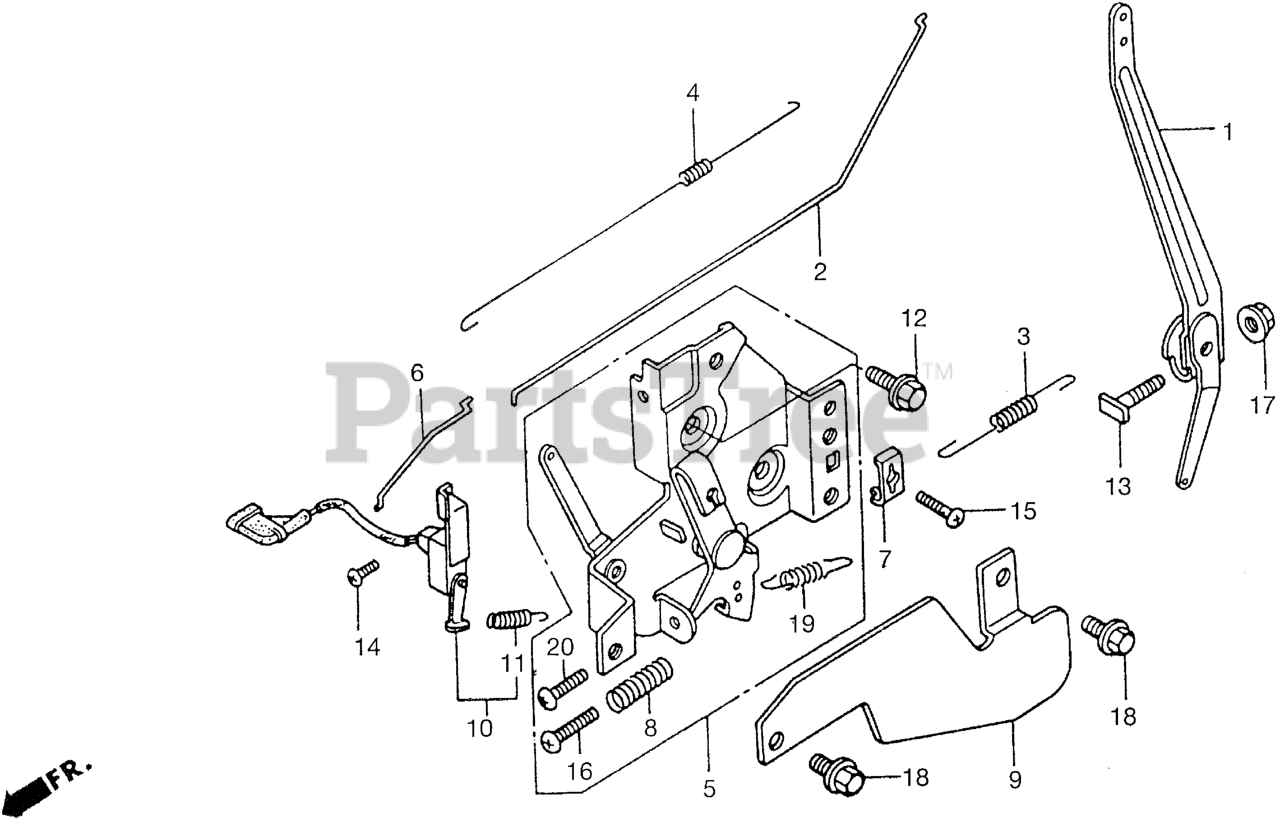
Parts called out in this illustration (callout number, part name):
1	ARM, GOVERNOR
2	ROD, GOVERNOR
3	SPRING, GOVERNOR
4	SPRING, THROTTLE RETURN
5	CONTROL
6	ROD, CHOKE
7	HOLDER, CABLE
8	SPRING, CONTROL ADJUSTING Use from Engine SN 2327377.
9	PROTECTOR, CONTROL
12	BOLT, FLANGE (6X14)
13	BOLT, GOVERNOR ARM
15	SCREW, PAN (5X16)
16	SCREW, PAN (5X20)
17	NUT, FLANGE (6MM)
18	BOLT, FLANGE (6X10)
19	SPRING, LEVER
20	SCREW, PAN (5X25)
